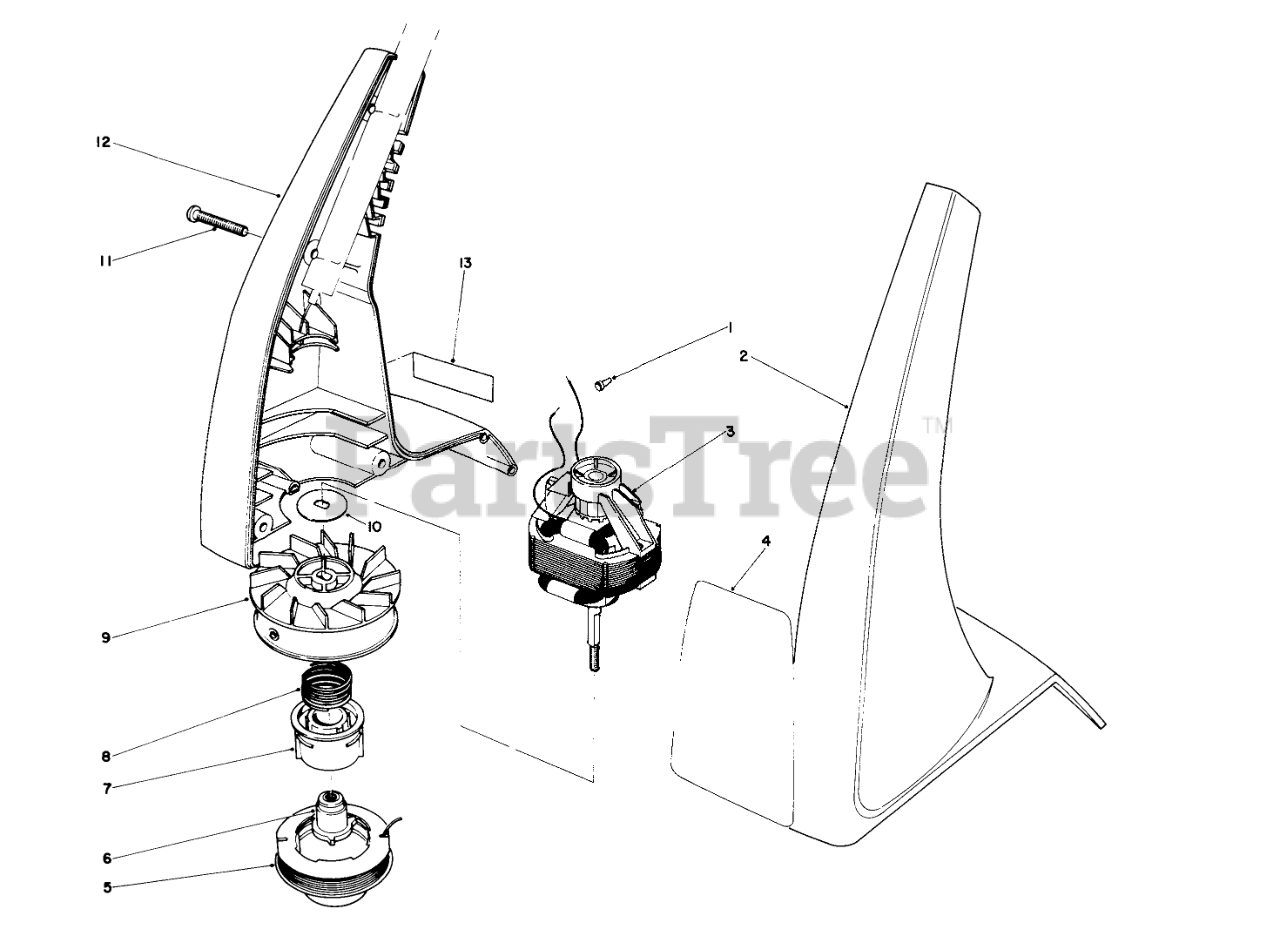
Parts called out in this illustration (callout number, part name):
1	CONNECTOR WIRE JOINT
2	L.H. HOUSING, 910
3	MOTOR, 910 TRIMMER
4	910 DECAL
5	Cutting Line (12- .05 Dia.)
6	DRIVER
7	CORE - SPOOL
8	Spring
9	Drum w/Eyelet
10	MOTOR WASHER
11	Screw
12	Housing-R.H.
13	Decal
